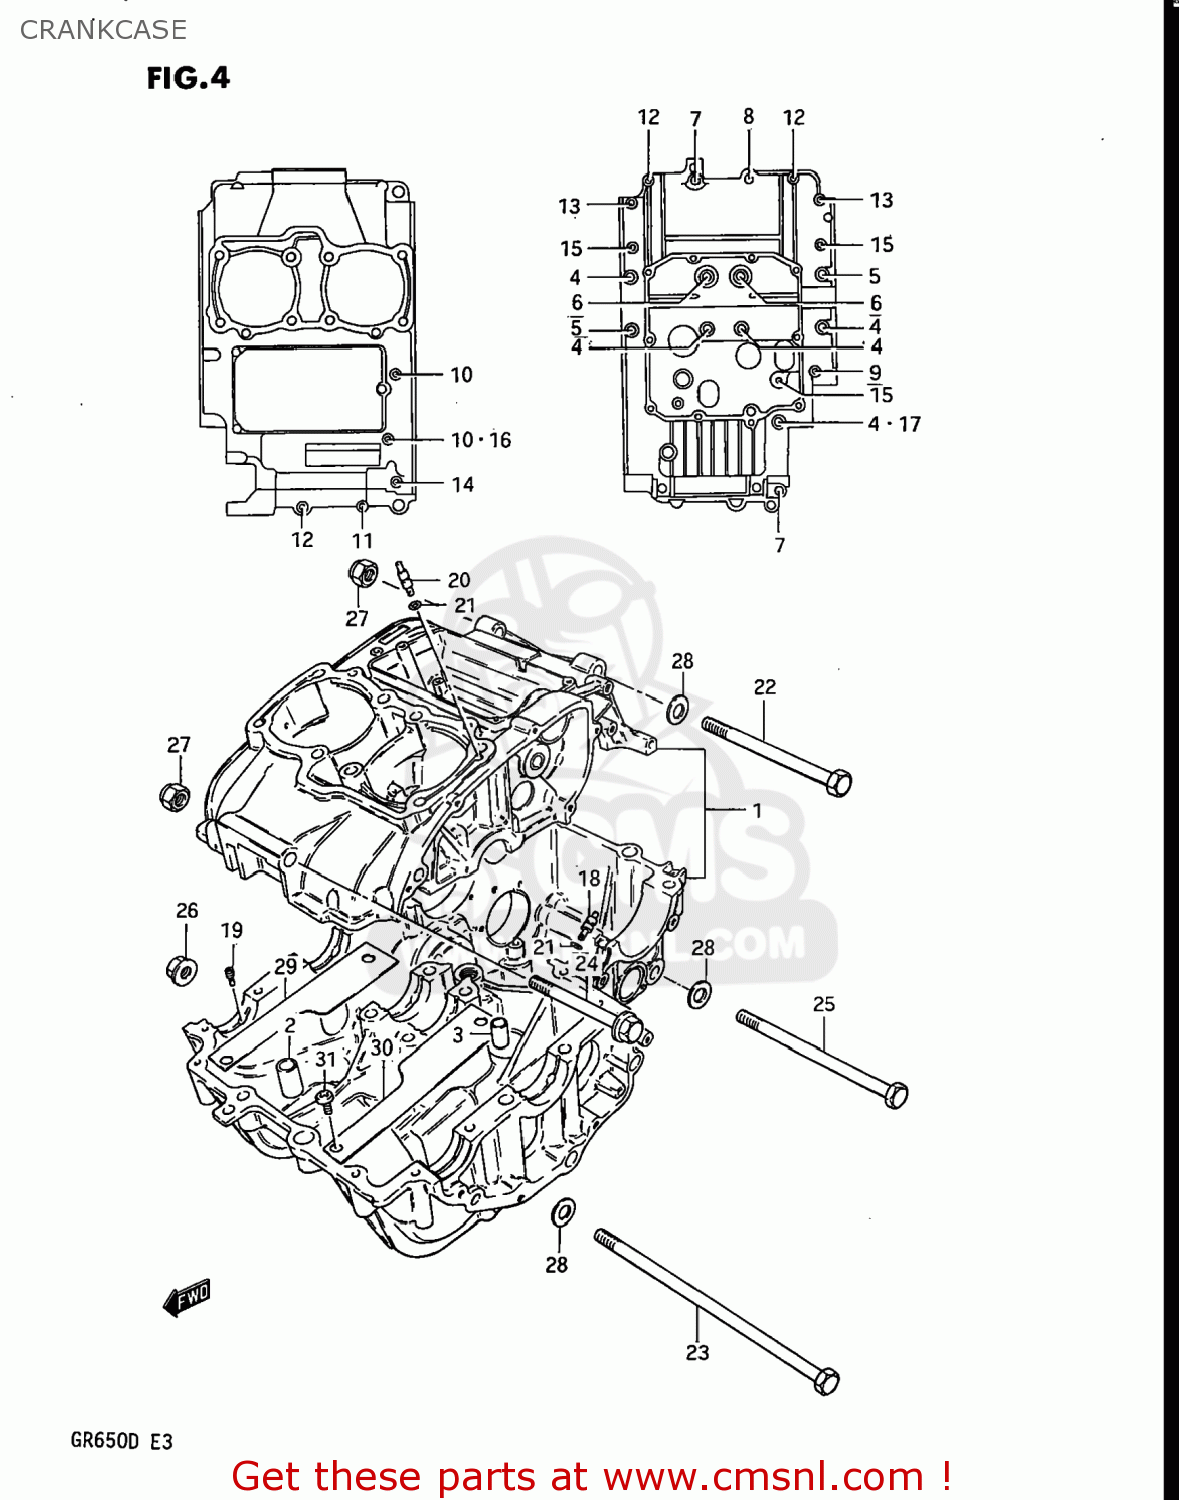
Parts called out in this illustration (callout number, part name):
1	CRANKCASE SET
2	PIN(10.4X13X22)
3	PIN (11X20)(SUS)
4	BOLT
5	BOLT
6	BOLT
7	BOLT (8X50)
8	BOLT 8X60
9	BOLT(6X100)
10	BOLT
11	BOLT (6X40)
12	BOLT 6X50
13	BOLT ,6X60
14	BOLT
15	BOLT (6X90)
16	GASKET(6.2X13X1.2) (NAS)
17	GASKET 8.2X14X1 (NAS)
18	JET,OIL GALLERY
19	JET,AIR
20	JET,AIR(14)
21	O RING(D:1.2,ID:4)
22	BOLT
23	BOLT
24	BOLT
25	BOLT 10X150
26	NUT 10MM
27	NUT
28	WASHER
29	PLATE,OIL SEPARATOR
30	PLATE,OIL SEPARATOR,LEFT
31	SCREW
